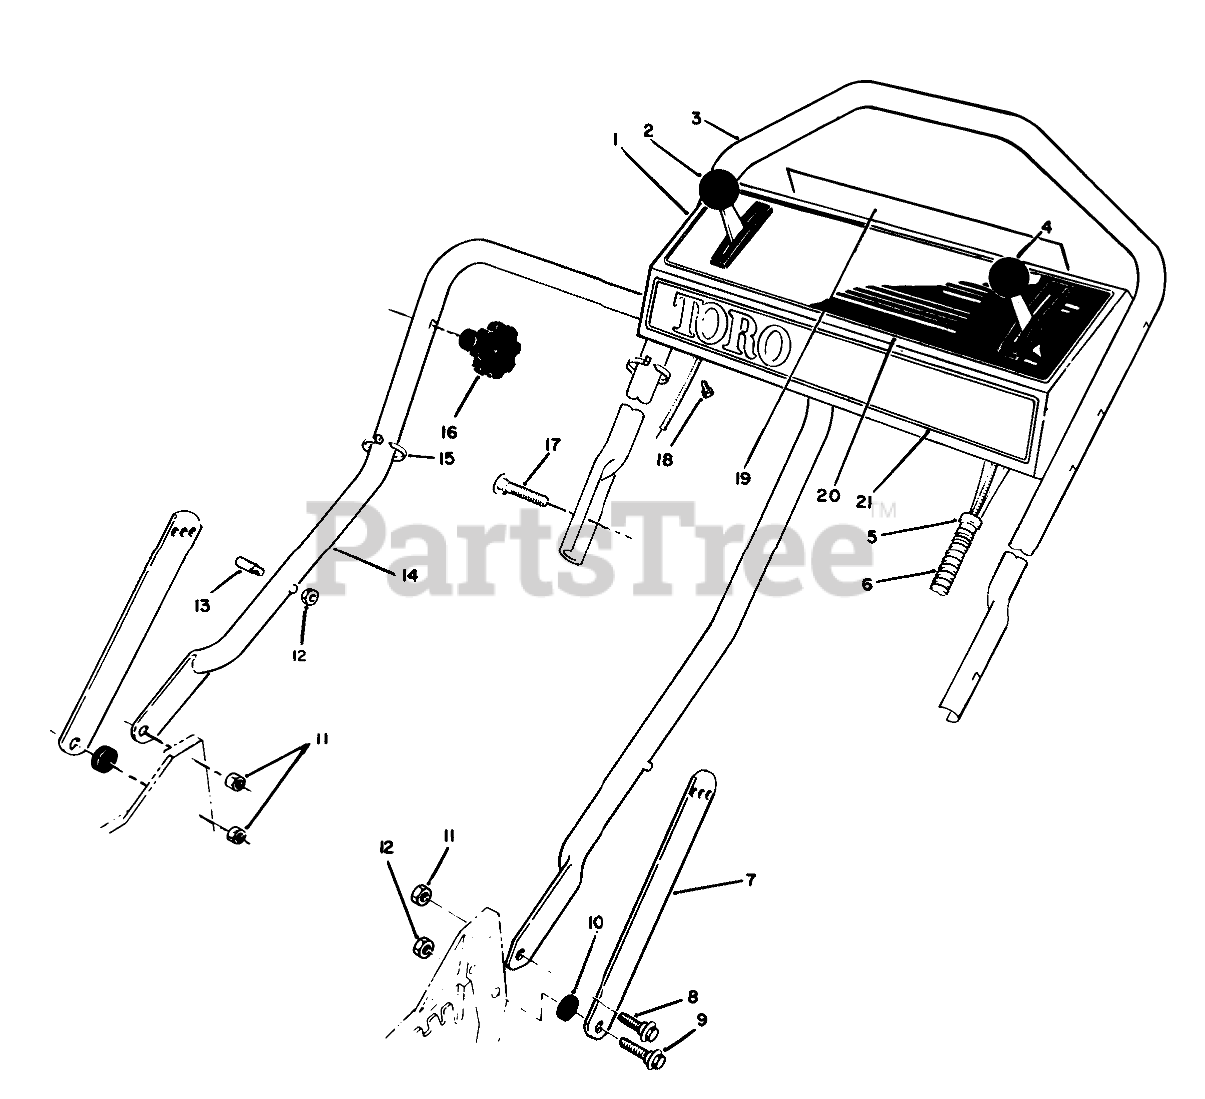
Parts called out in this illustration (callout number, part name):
1	Panel-Control (Incl. Ref. #19 & 20)
2	GROUND SPEED CONTROL
3	Handle-Upper
4	THROTTLE CONT-SERVICE
5	FITTING-RING
6	CONTROL CABLE COVER
7	Handle Latch
8	SCREW-SHOULDER
9	SCREW-SHOULDER
10	SPACER
11	NUT-LOCK, NI
12	NUT-LOCK, NI
13	HANDLE PIN
14	LOWER HANDLE ASM
15	TIE-CABLE
17	5/16-18 X 2 HNDLE SCREW
18	SCREW-HWHTF
19	DECAL - PANEL, REAR
20	Decal-Instruction
21	DECAL - TORO PANEL
